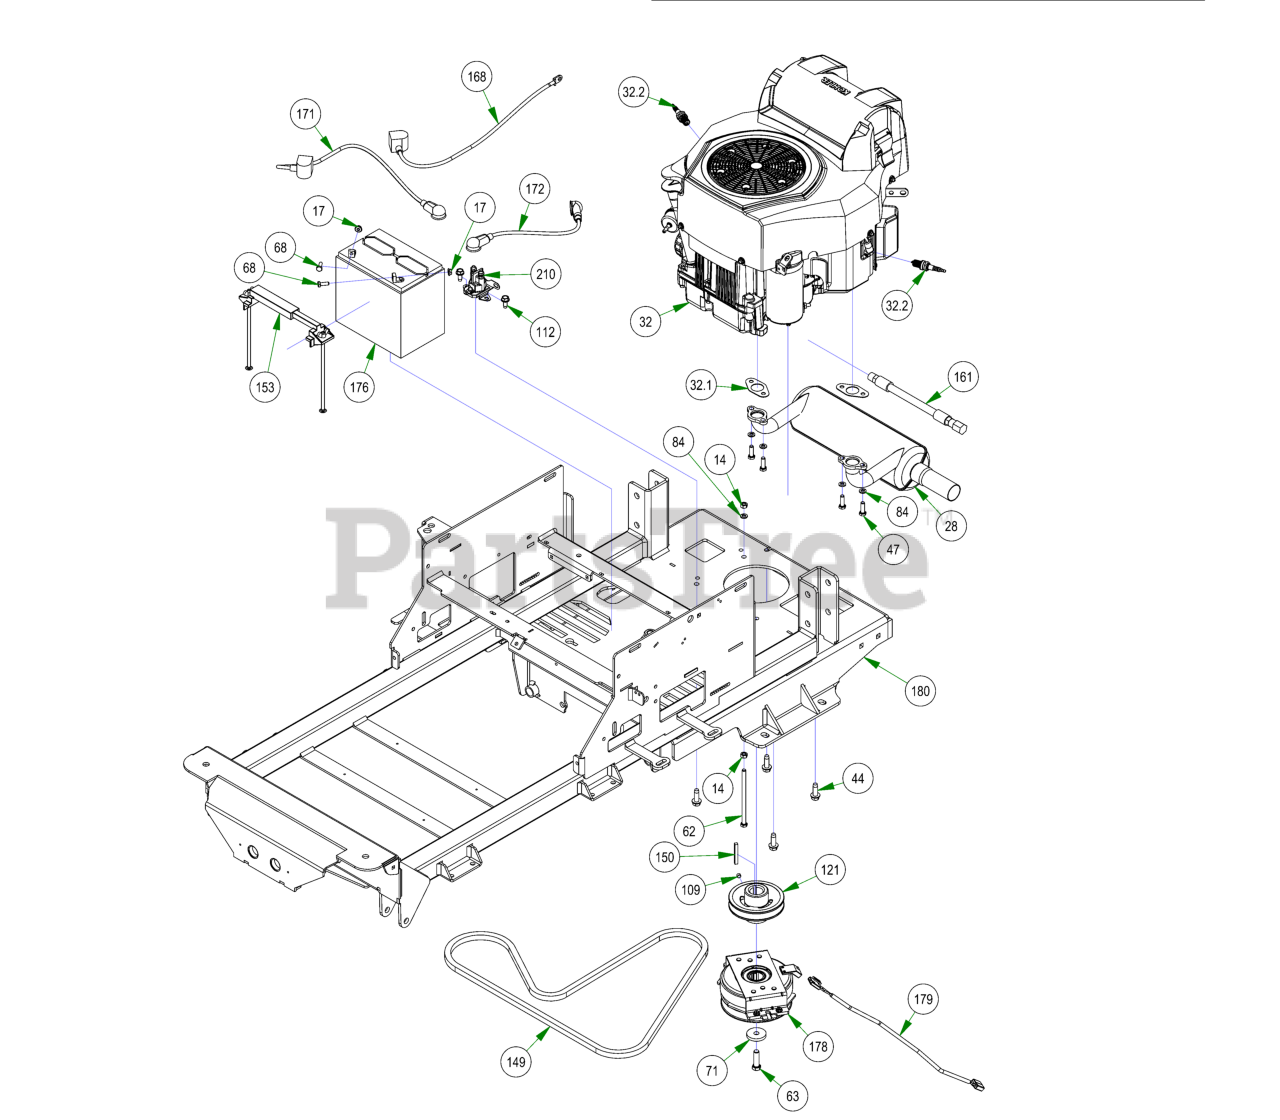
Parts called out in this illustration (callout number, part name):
14	5/16-18 HEX NUT ZINC
17	1/4-20 HEX SERRATED FLANGE NUT HARD/ZINC
28	Kohler Muffler
32	Kohler-2014 CZT/Outlaw 747cc
32.1	Exhaust Gasket
32.2	Spark Plug
44	3/8-16 X 1-1/8 HEX WASHER UNSLOT SERRATED (TRI-LOB) TRS ZINC YELLOW
47	5/16-18 X 1 HEX CAP SCREW (GR.5) ZINC
62	5/16-18 X 5-1/2 HEX CAP SCREW (GR.5) ZINC
63	7/16-20 X 1-1/2 HEX CAP SCREW (GR.8) w/ Patch
68	1/4-20 X 3/4 HEX CAP SCREW (GR.5) ZINC
71	CLUTCH WASHER
84	5/16 SPLIT LOCKWASHER ZINC
109	5/16-24 X 1/4 SOCKET SET SCREW (CUP PT) PLAIN
112	5/16-18 X 3/4 HEX WASHER SLOT (F) TCS ZINC
121	4 3/4 Motor Pulley
149	75.8" Pump Belt
150	1/4 X 2 SQ MACHINERY KEY 1018 STL PLAIN
153	Hold Down Assembly
161	Oil drain Hose
168	24 inch Black Cable – MZ/ZT
171	24" Red Battery Cable
172	12" Red Battery Cable
176	SP-35 Battery
179	Clutch Pigtail
180	2022 Maverick Frame - Painted
